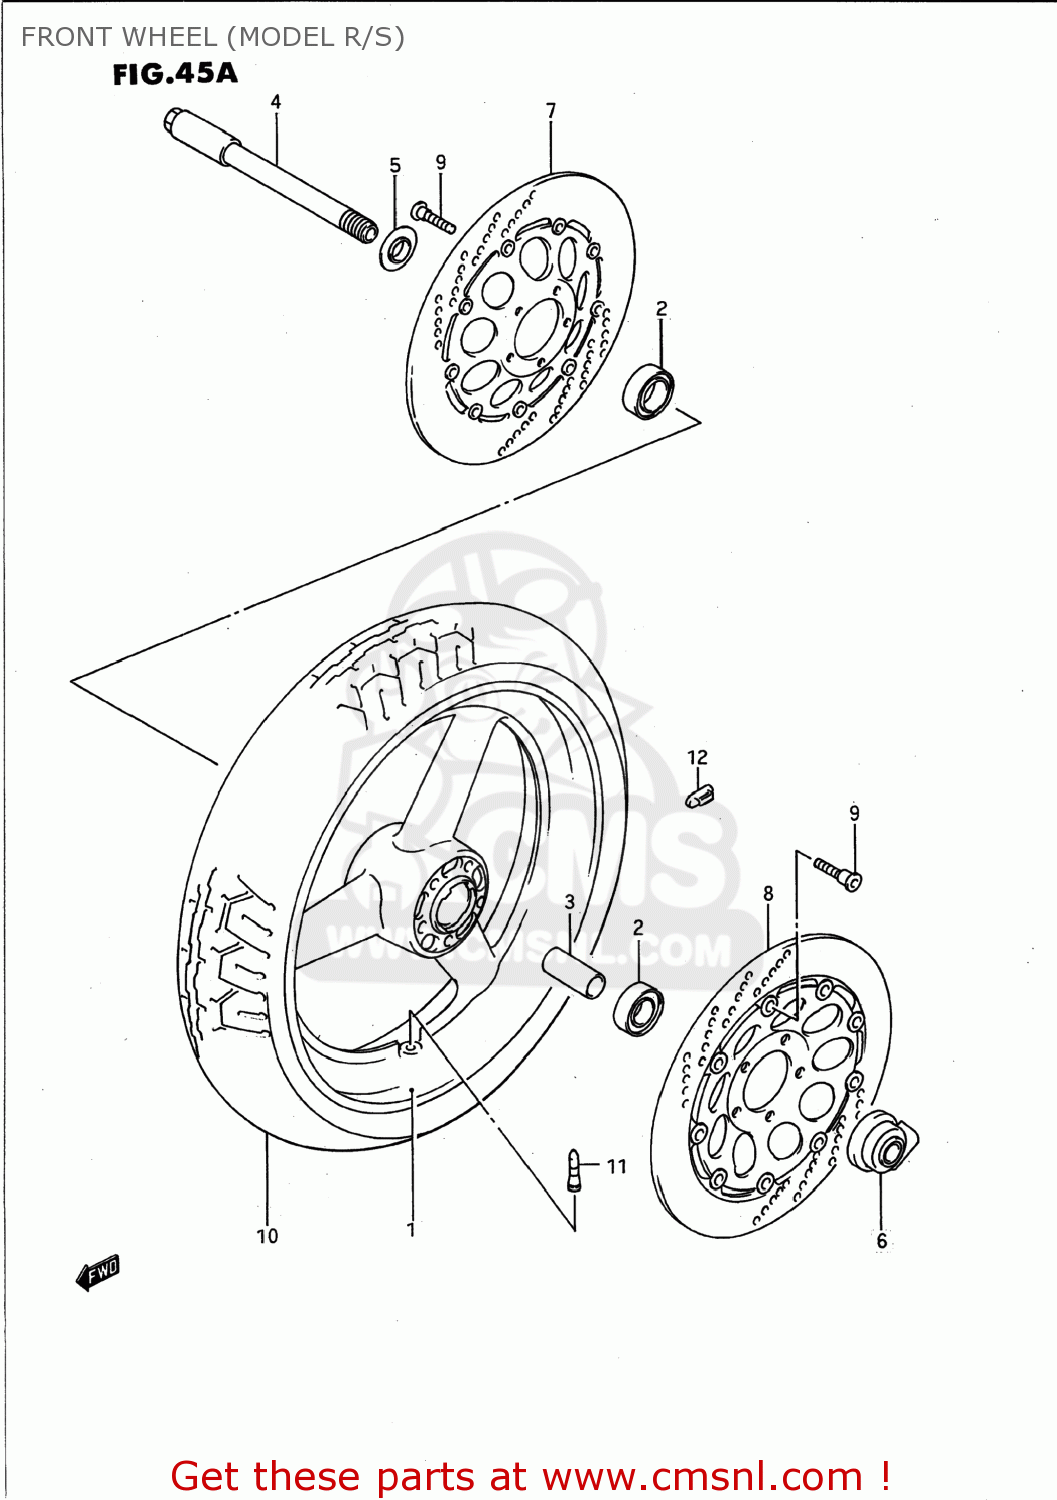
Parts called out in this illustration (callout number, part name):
1	WHEEL,FRONT
2	BEARING
3	SPACER(20.8X27.2X74)
4	AXLE,FR
5	SPACER,FR HUB BEARING,R
6	BOX ASSY,SPEEDOMETER GEAR
7	DISC,FR BRAKE,R
8	DISC,FR BRAKE,L
9	BOLT 8X33
10	TIRE,FRONT 120/70ZR17 D20
11	VALVE ASSEMBLY,WHEEL,TR412
12	BALANCER,WHEEL
